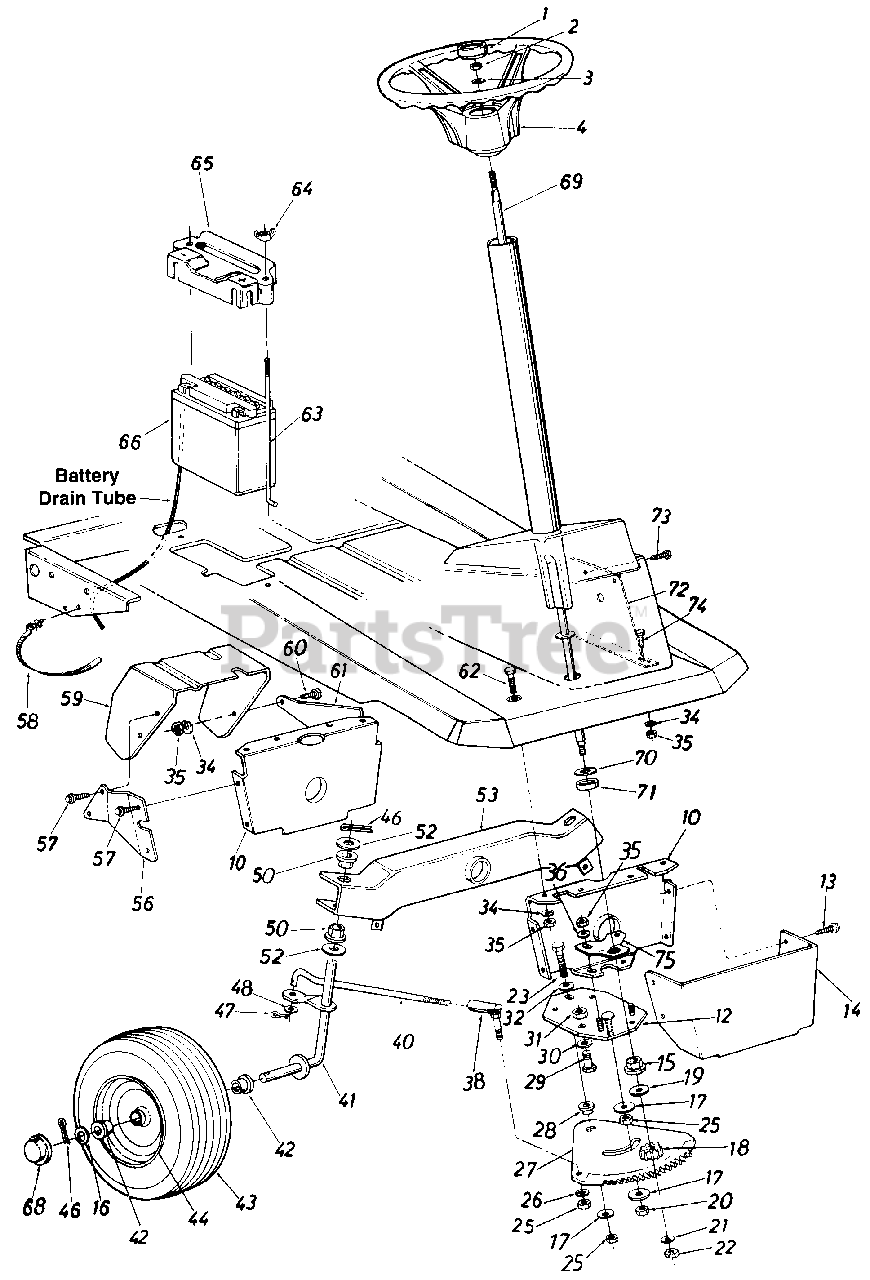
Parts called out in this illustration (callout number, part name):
1	Steering Wheel Cap
2	Hex L-Nut 5/16-24 Thd.
3	Bell-Wash. .345" I.D. x .88" O.D.
4	Steering Wheel Ass'y.
16	Fl-Wash. .64" I.D. x 1.5" O.D.
17	Fl-Wash. 3/8" I.D. x 1.37" O.D.
18	Steering Pinion Gear
19	Fl-Wash. .51" I.D. x 1" O.D.
20	Hex L-Nut 3/8-24
21	Fl-Wash. .34" I.D. x .68" O.D.
22	Hex L-Nut 5/16-24 Thd.
23	Hex Bolt 3/8-24 x 1.5" Lg. (Grade 5)
25	Hex Nut 3/8-24 Thd.
26	L-Wash. 3/8" I.D.
27	Steering Gear Segment
28	Shoulder Spacer .622" Dia. x .218
29	Hex Bolt (Nylon) 1/2-13 x .75"
30	Fl-Wash. .530" I.D. x .930"
31	Hex Nut 1/2-13 Thd.
32	Bell-Wash. .385" I.D. x .88"
34	L-Wash. 5/16" I.D.
35	Hex Nut 5/16-18 Thd.
36	Spr. Wash. .32" I.D. x .62" O.D.
38	Ball Joint Ass'y. 3/8-24 Thd.
40	Steering Tie Rod
41	Front Axle Ass'y. - R.H.
42	Flange Bearing .632" I.D.
43	Front Wheel Ass'y. Comp.
44	Front Wheel Rim Only
46	Cotter Pin 1/8" Dia. x 1.25"
47	Cotter Pin 1/8" Dia. x 1.00"
48	Fl-Wash. .385" I.D. x .87"
50	Hex Flange Bearing
52	Fl-Wash. .635" I.D. x 1.12"
53	Pivot Bar Ass'y.
58	Cable Tie
59	Clutch-Brake Pedal Ass'y.
60	Hex Bolt 5/16-18 x .75" Lg.
63	Battery Hold Down Rod
64	Wing Nut Solid 1/4-20 Thd.
65	Battery Hold Down Cover
66	12V Battery
68	Hub Cap
69	Steering Shaft Ass'y.
70	Fl-Wash. .62" I.D. x 1.25" O.D.
71	Spacer (Plastic)
74	Hex Bolt 5/16-18 x 2.00" Lg.
75	Steering Gear Adjuster Ass'y.
